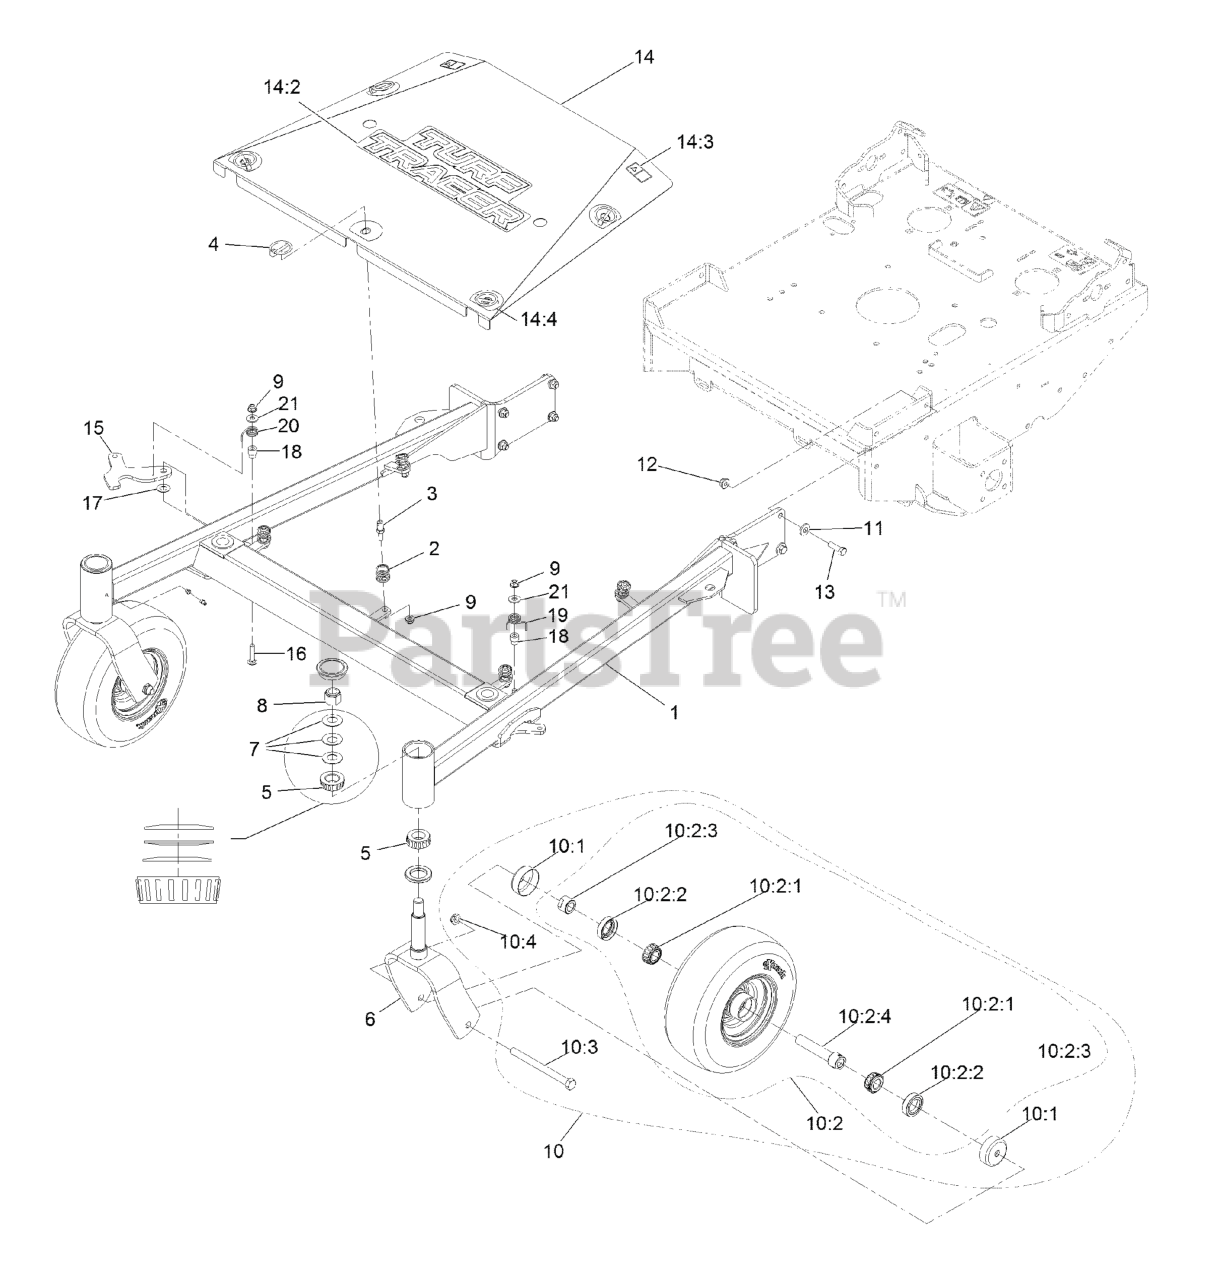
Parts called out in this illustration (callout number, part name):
1	ASM, FRONT FRAME W/ BEARI
3	PIN-SPRING
4	PIN-LYNCH
5	Cone-Bearing Tapered Roller
6	WLD, CASTER FORK
7	WASHER-BELLVILLE
8	NUT-LOCK, NI
9	NUT-HF, NI
10	ASM,WHEEL&BEARINGS
10:1	GUARD-SEAL
10:2	Wheel And Bearing ASM
10:2:1	BEARING-CONE, TAPERED ROLLER
10:2:2	SEAL-CASTER
10:2:3	SPACER-NUT
10:2:4	CASTER AXLE ASM
10:3	SCREW-HH
10:4	NUT-HEX
11	WASHER-BELLEVILLE
12	NUT-HF, NI
13	SCREW-HH
14	ASM, CENTER SHIELD W/ DEC
14:2	DECAL-TURF TRACER
14:3	DECAL-WARNING
14:4	DECAL-SCRATCH COVER
15	LATCH, DECK HEIGHT
16	BOLT-CARR
17	Washer-Plastic
18	Collar-Basket
19	Spring-Torsion, LH (Yellow)
20	Spring-Torsion, RH
21	WASHER-FLAT
